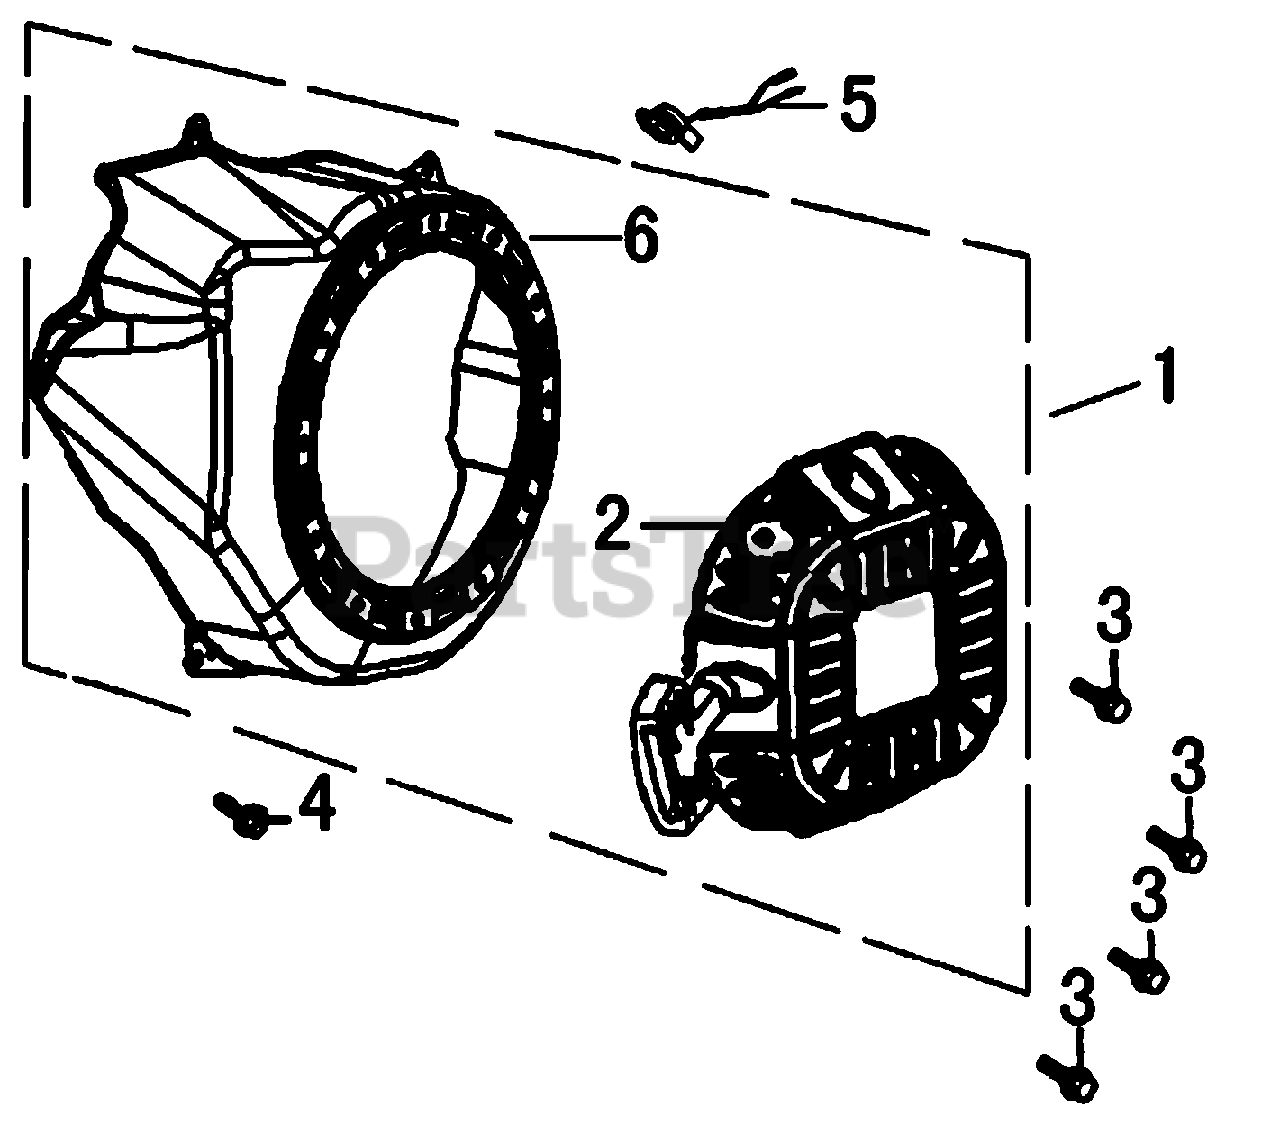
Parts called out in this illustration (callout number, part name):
1	RECOIL STARTER W/BLWR HOUSING
2	RECOIL COVER ASSY-G200F
3	BOLT, FLANGE 6X8
4	BOLT, FLANGE 6X10
5	SWITCH ASSY., ENGINE STOP
6	BLOWER HOUSING/SHROUD
